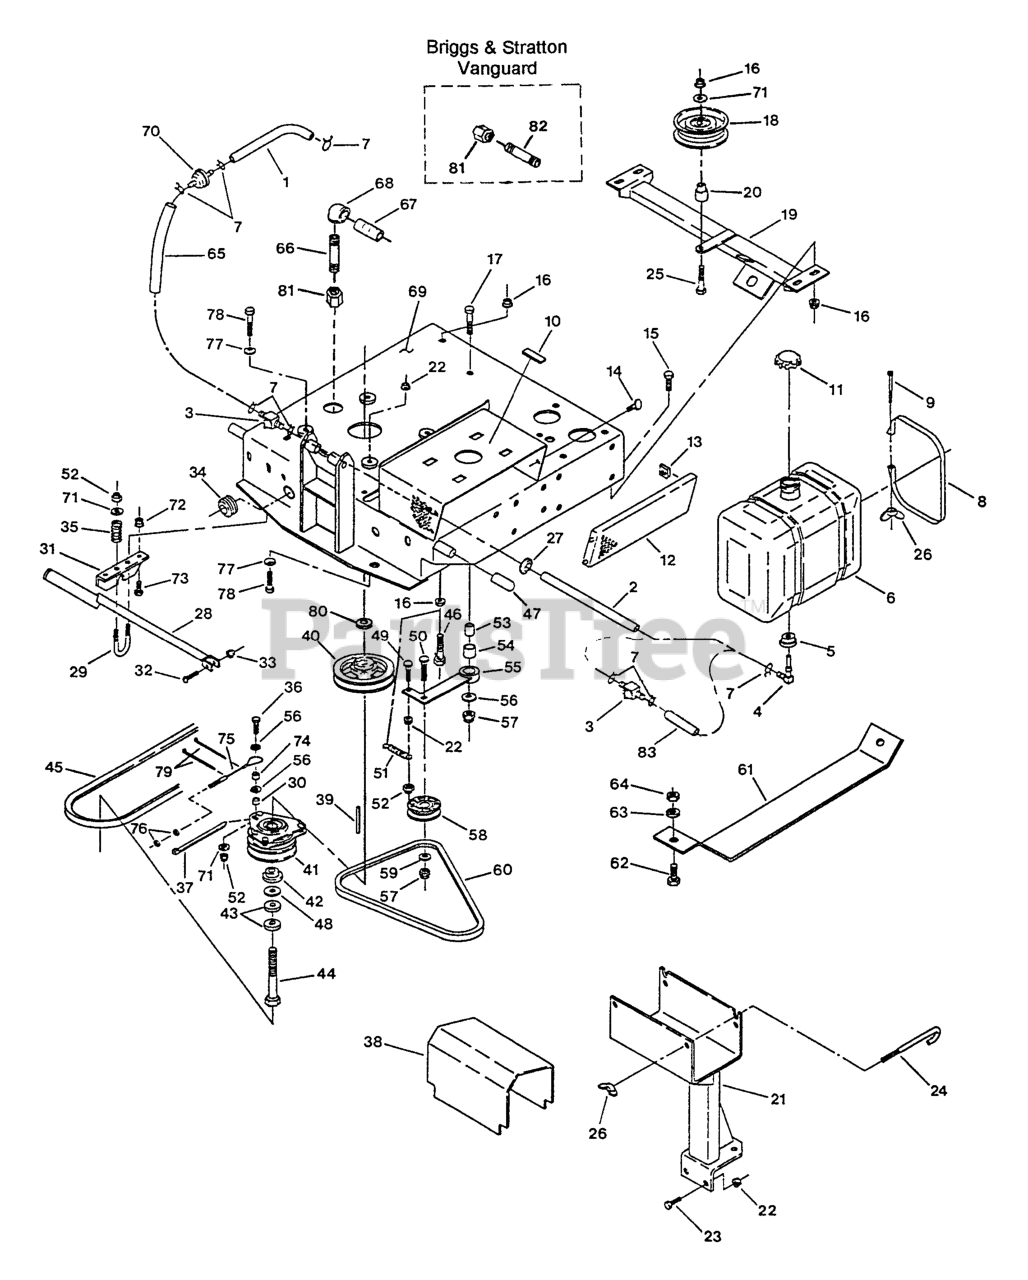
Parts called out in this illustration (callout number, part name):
1	FUEL LINE
3	VALVE-FUEL
4	ELBOW-TANK, FUEL
9	SCRW,MACH CRPH
10	PAD,PLASTIC TANK
11	CAP-FUEL
13	NUT,RETNR UTYP 1/4-20
14	SCREW,REGTHMB,
19	WLD,CROSSMEMBER
20	BUSHING,IDLER
21	WLD,BATTERY MOUNT
24	BOLT - HOLD DOWN
26	WINGNUT
27	GROMMET
30	SPACER,CLUTCH ANCHOR
34	GROMMET
35	SPRING-COMPRESSION
37	TIE-PLASTIC
40	SHEAVE,4.25 OD A
42	BUSHING,CLUTCH KEEPER
43	WASHER-SPRING
45	BELT,BLADE DRIVE
47	GRIP-LEVER, DRIVE
51	SPRING,EXTENSION
53	BUSHING,STEEL
54	BUSHING,IDLER ARM
55	WLD,IDLER ARM HYDRO
58	IDLER,PULLEY
60	BELT,A TRANS DRIVE
61	PLATE-SKID
67	NIPPLE,PIPE
68	ELBOW-90 DEG
77	WASHER-SPRING
79	TIE-CABLE
81	CAP-HEX
